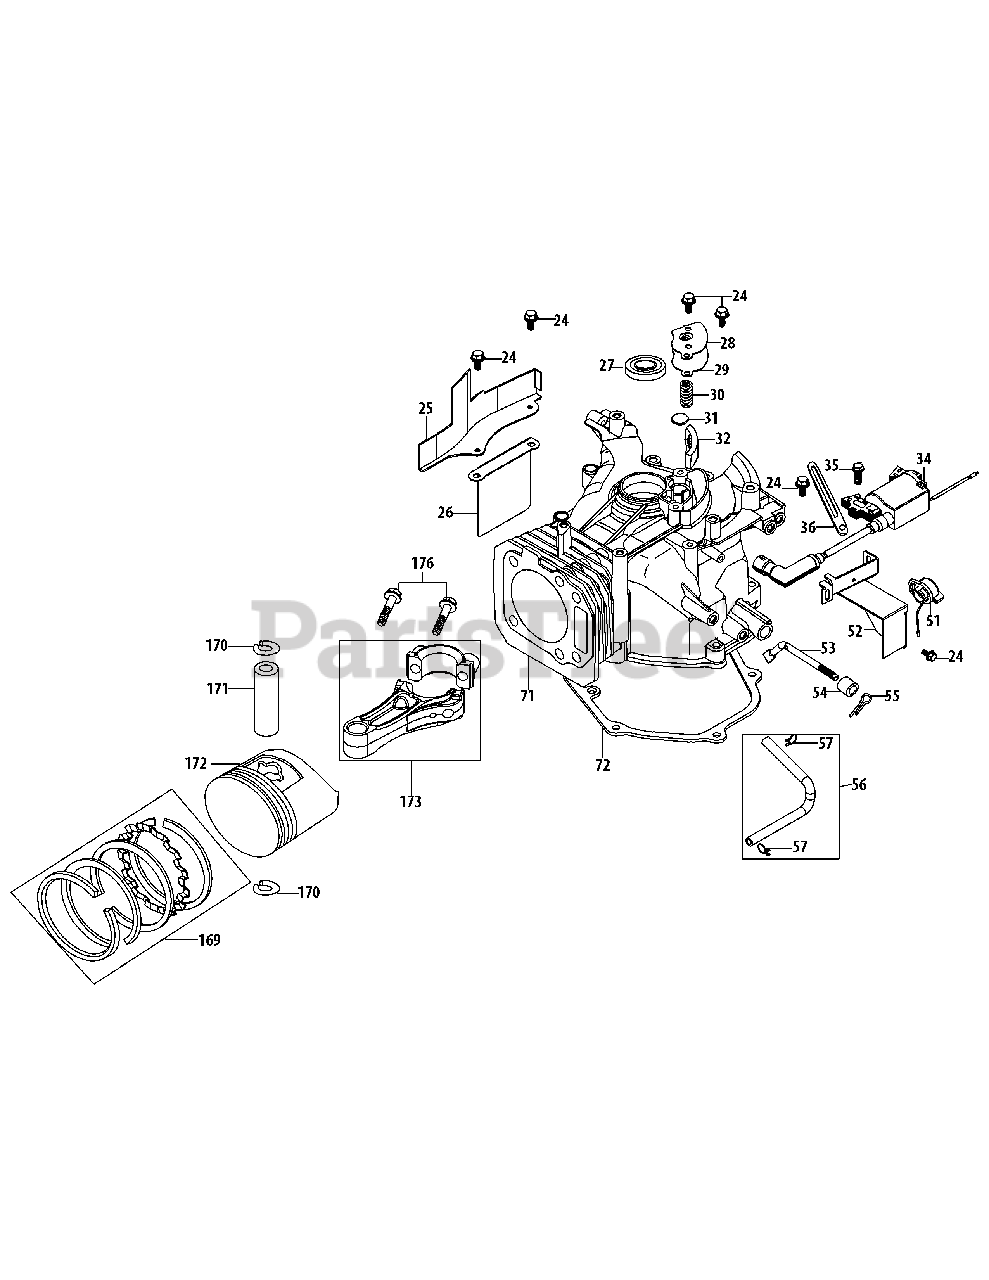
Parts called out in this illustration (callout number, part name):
24	Bolt M6X14
25	Engine Brake Cover Plate
26	Label Bracket
27	Upper Crankshaft Seal
28	Breather Cover Plate
29	Breather Gasket
30	Breather Spring
31	Breather Valve
32	Mesh Screen
34	Ignition Coil Assembly
35	Bolt M6X18
36	Flexible Clamp
51	Ignition Switch
52	Fuel Tank / Console Bracket
53	Governor Arm Shaft
54	Governor Seal
55	Governor Shaft Cotter Pin
56	Breather Hose Assembly
57	Breather Hose Clamp
71	Short Block Assembly
72	Crankcase Cover Gasket
169	Piston Ring Set
170	Piston Pin Snap Ring
171	Piston Pin
172	Piston
173	Connecting Rod Assembly
176	Connecting Rod Bolt
